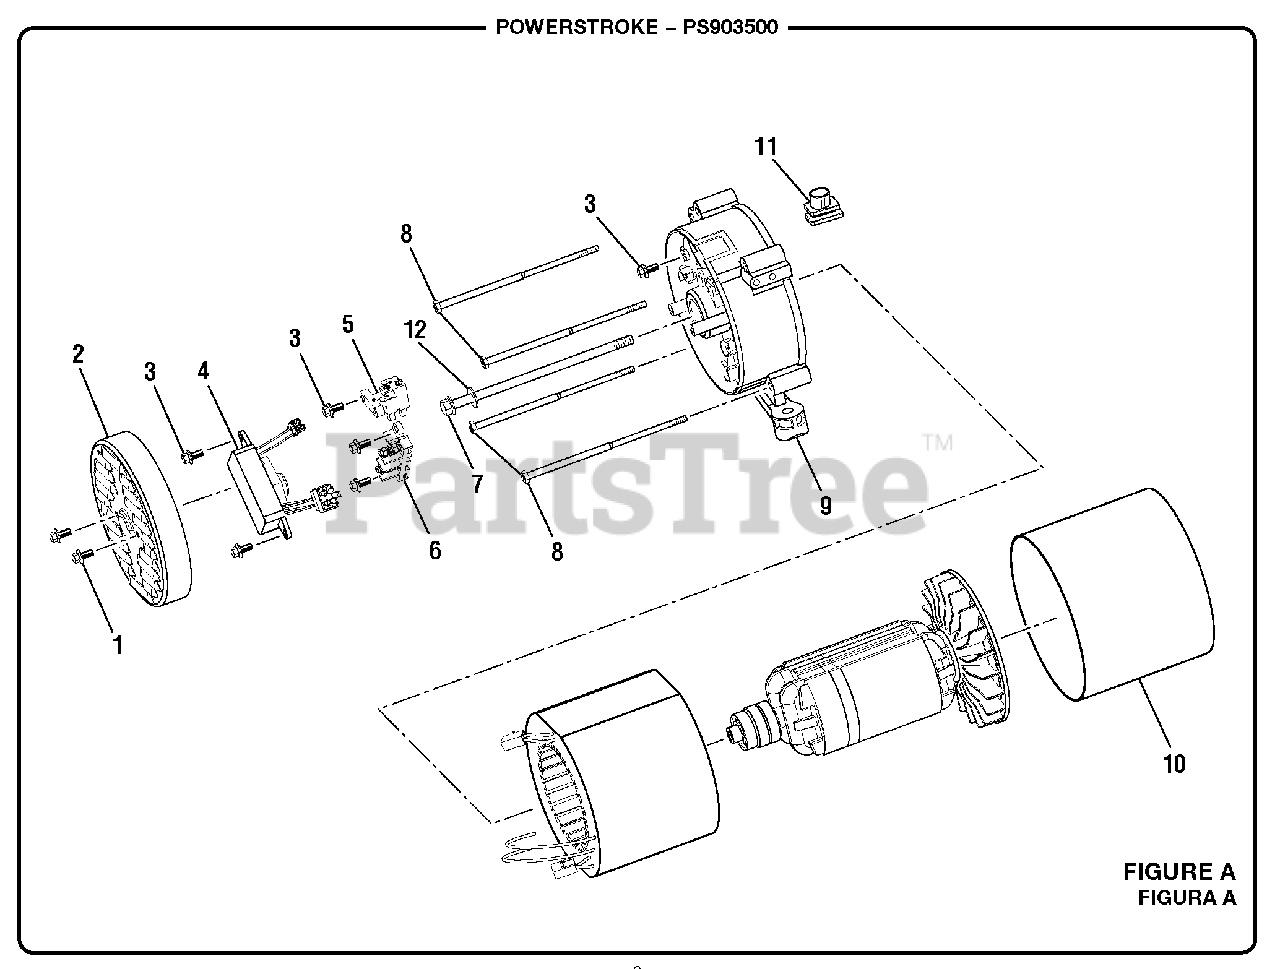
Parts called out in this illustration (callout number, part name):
1	Bolt (M5 x 16 mm, Hex Hd.)
2	Brush Cover
3	Bolt (M5 x 10 mm)
4	Automatic Voltage Regulator
5	Brush Assembly
6	Terminal Block
7	Rotor Bolt
8	Stator Bolt
9	Bearing Housing
10	Generator Head Cover
11	Rubber Boot
12	Lock Washer (Rotor)
